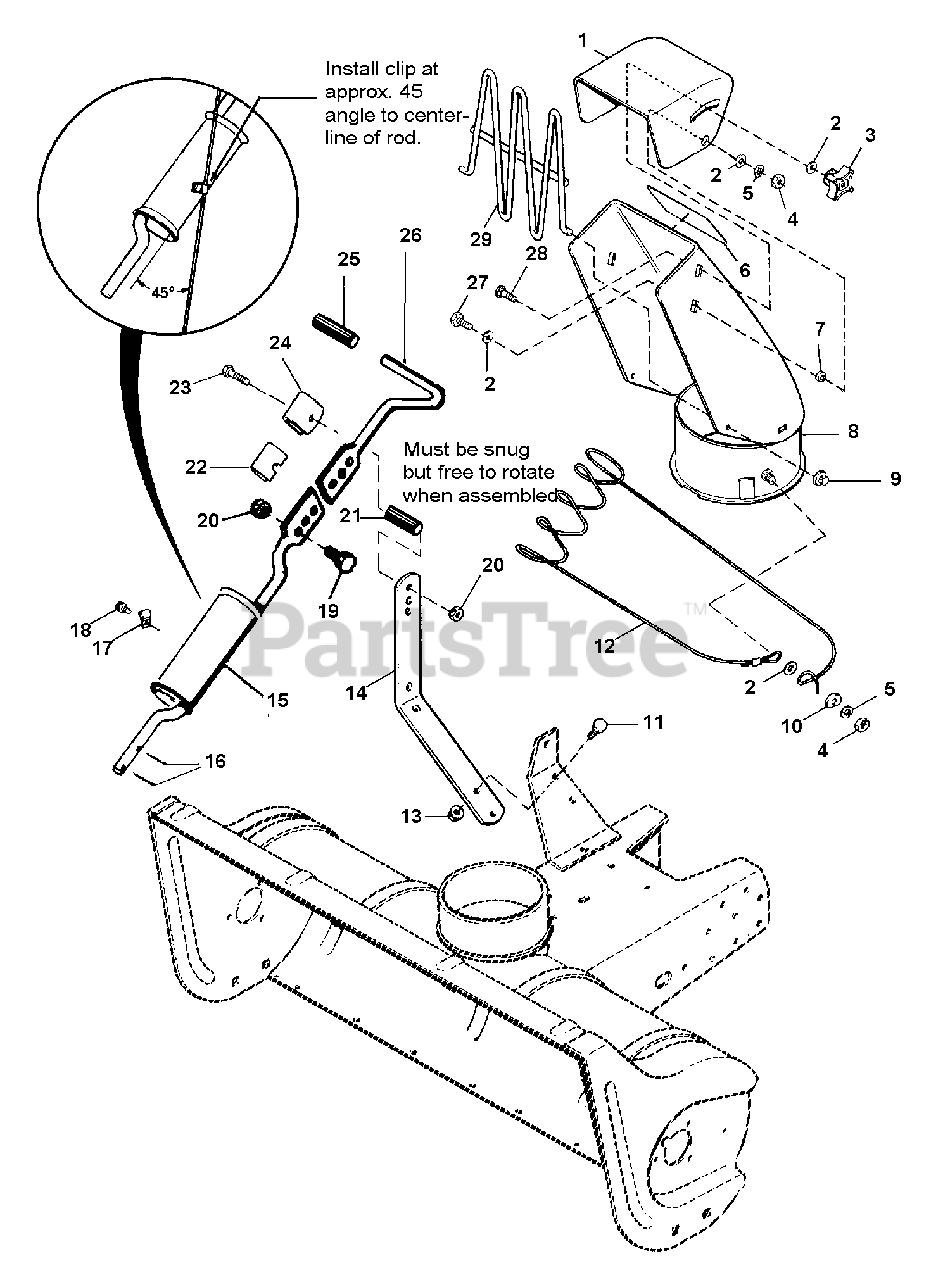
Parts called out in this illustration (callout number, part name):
1	DEFLECTOR
2	WASHER, 5/16
6	DECAL, Blower Housing
8	CHUTE ASSEMBLY
9	PUSH NUT, 1/4
10	WASHER, Cup
11	CAPSCREW, Hex Head, 3/8-16 x 1
12	CABLE ASSEMBLY
13	NUT, Hex Flange, 3/8-16
14	ARM, Support
15	ROD ASSEMBLY, Spout
16	COTTER PIN, 3/32 x 3/4
18	SCREW, Hex, Taptite, 1/4-20 x 3/8
19	CAPSCREW, Hex Head, 5/16-18 x 7/8
20	NUT, Hex, Flange Lock, 5/16-18
23	CAPSCREW, Hex Head, 5/16-18 x 3-1/2
25	GRIP, Handle
26	HANDLE, Spout Control
28	CARRIAGE BOLT, 5/16-18 x 1
29	GUARD ASSEMBLY, Chute
